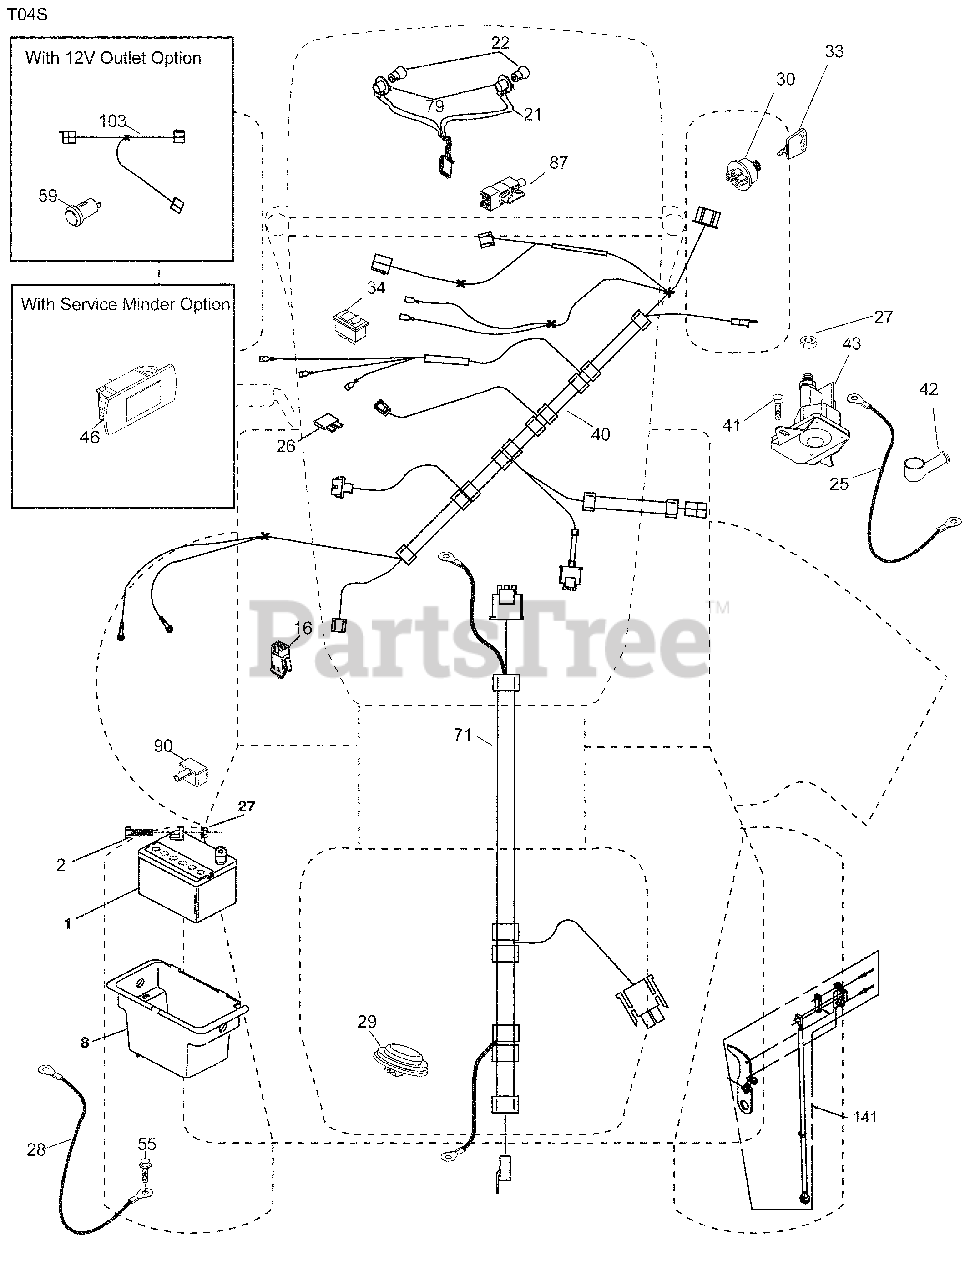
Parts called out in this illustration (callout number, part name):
1	Battery
2	Bolt Hex Head 1/4-20 x 3/4
8	Box Battery
16	Switch Interlock Push-In
21	Harness Socket Light w/4152J
22	Bulb Light
25	Cable Starter
27	Nut Keps Hex 1/4-20 unc
28	Cable, Ground
29	Switch, Seat
30	Switch, Ign
33	Key/Chain
34	Switch Light/Reset
40	Harness Ign. Dash
41	Screw Thd Cut 1/4-20 x 1/2
42	Cover, Terminal
43	Solenoid
46	Gauge Servicereminder Hrmtr
55	Screw Thdrol 5/16-18 x 3/4 TYTT
71	Harness Ign.
79	Socket Asm. Bulb
87	Switch Interlock
90	Cover Terminal
141	Kit T2 ROS
